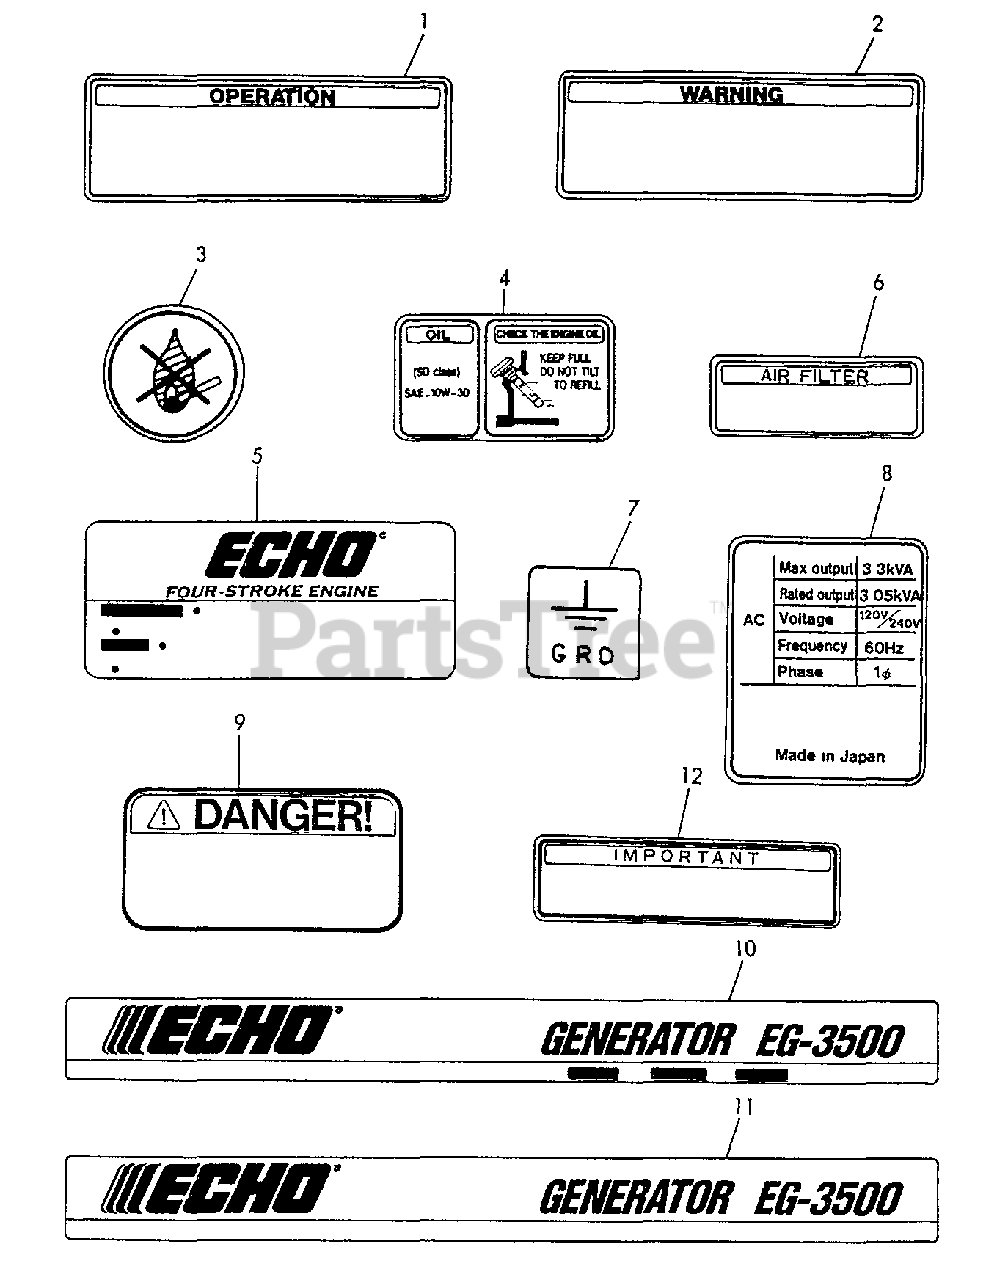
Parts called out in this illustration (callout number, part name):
1	LABEL - OPERATION
2	LABEL - WARNING
3	LABEL - NON FIRE
4	LABEL - OIL
5	LABEL - ECHO
6	LABEL - AIR CLEANER
7	LABEL - GROUND
8	LABEL - GENERATOR
9	LABEL - DANGER
10	LABEL - GENERATOR
11	LABEL - GENERATOR
12	LABEL - IMPORTANT
